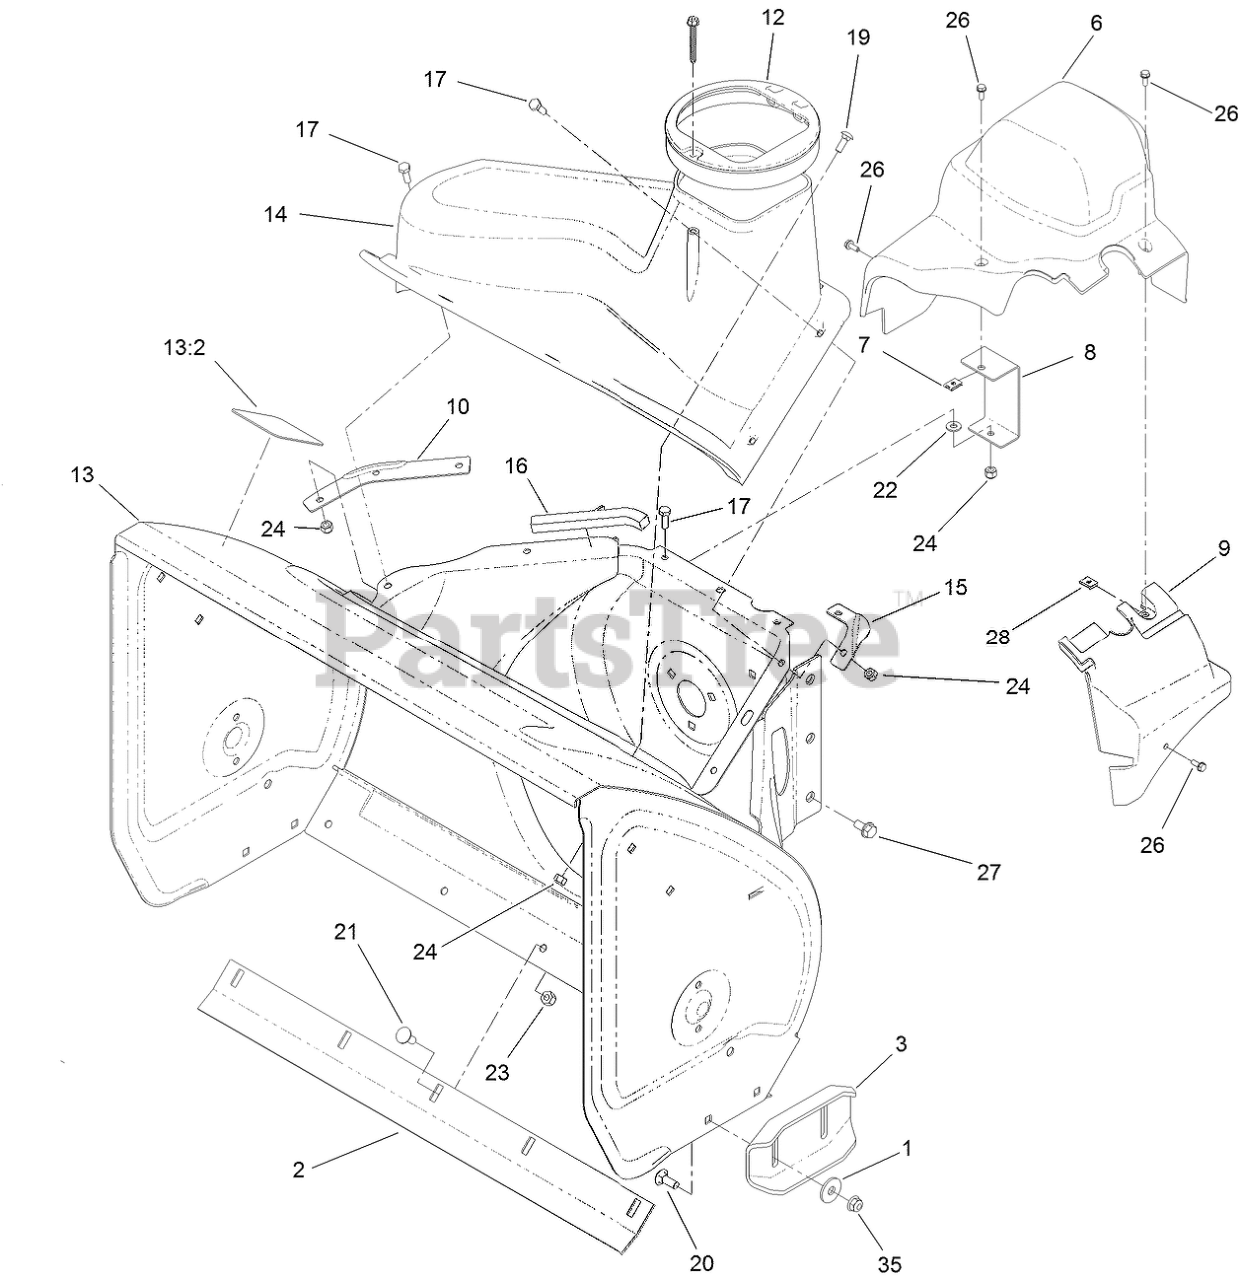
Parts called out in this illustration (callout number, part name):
1	WASHER-FLAT
2	SCRAPER-FIXED
6	COVER-BELT
7	NUT-SPEED
8	BRACKET-COVER, CLIP NUT
9	COVER-EXTENSION, BELT
10	SEAL-FLANGE, COVER
12	GUIDE-CHUTE
13	HOUSING-AUGER, 26 INCH
13:2	DECAL-DANGER, AUGER
16	SEAL-HOUSING
17	SCREW-HH
19	BOLT-CARR
20	BOLT-CARR
21	BOLT-CARR
22	WASHER-FLAT
23	NUT-HEX
24	NUT-HEX
26	SCREW-HWH
27	SCREW-HWHTF
28	NUT-SPEED
35	NUT-HF
